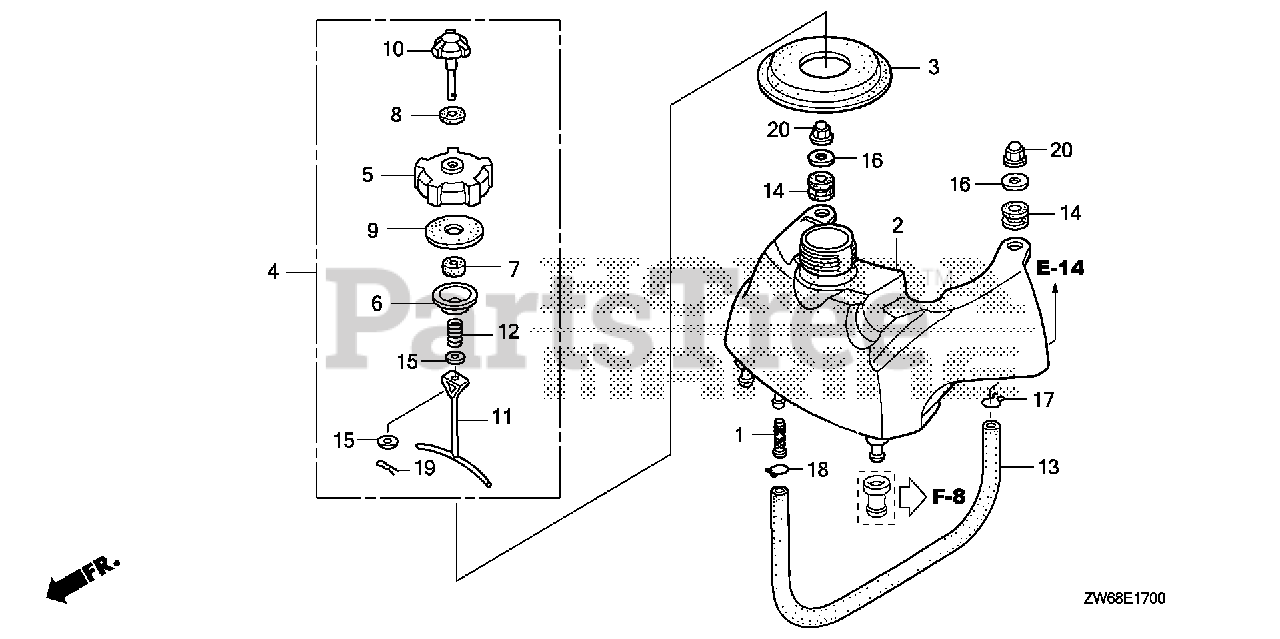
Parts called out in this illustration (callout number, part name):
13	TUBE, FUEL
17	CLIP, TUBE (B10)
18	CLIP, TUBE (B12)
